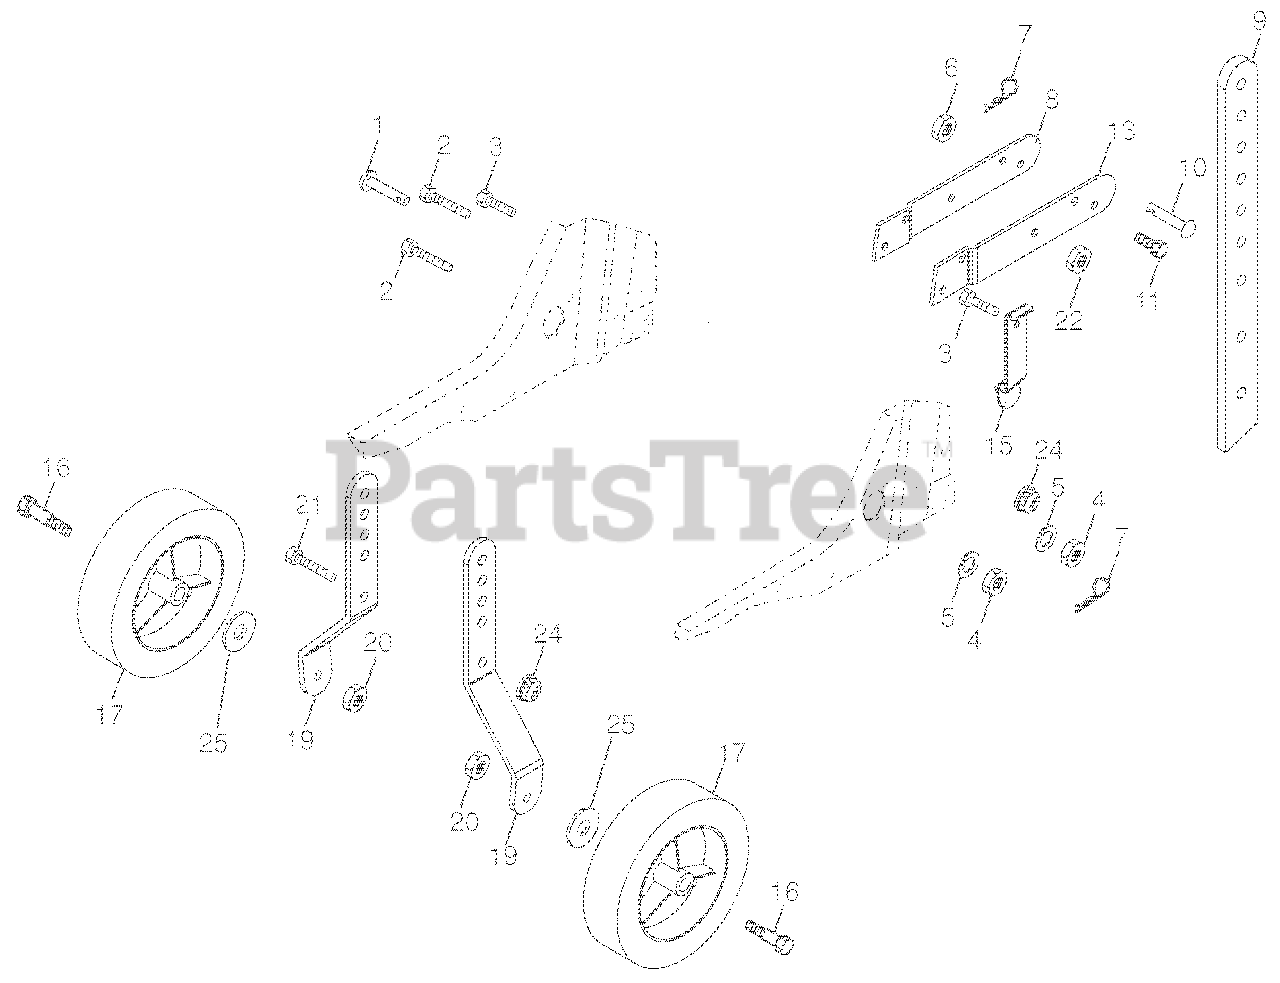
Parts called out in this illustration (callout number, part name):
1	Pin, Clevis
2	Bolt, Hex Head 5/16-18 x 1-1/4
3	Bolt, Hex Head 5/16-18 x 3/4
4	Nut, Hex 5/16-18
5	Washer, Lock 5/16
6	Locknut, Washer Insert 3/8-16
7	Clip, Hairpin
8	Support, Depth Stake, R.H.
9	Stake, Depth
10	Pin, Clevis
11	Bolt, Hex Head 3/8-16 x 1-3/4
13	Support, Depth Stake, L.H.
15	Spring, Stake
16	Bolt, Shoulder
19	Bracket, Wheel
20	Nut, Hex, Crownlock 3/8-16
21	Bolt, Hex Head 5/16-18 x 1
22	Locknut, Washer Insert 5/16-18
24	Nut, Hex, Flangelock
25	Washer, 17/32 x 7/8 x 16 Ga.
